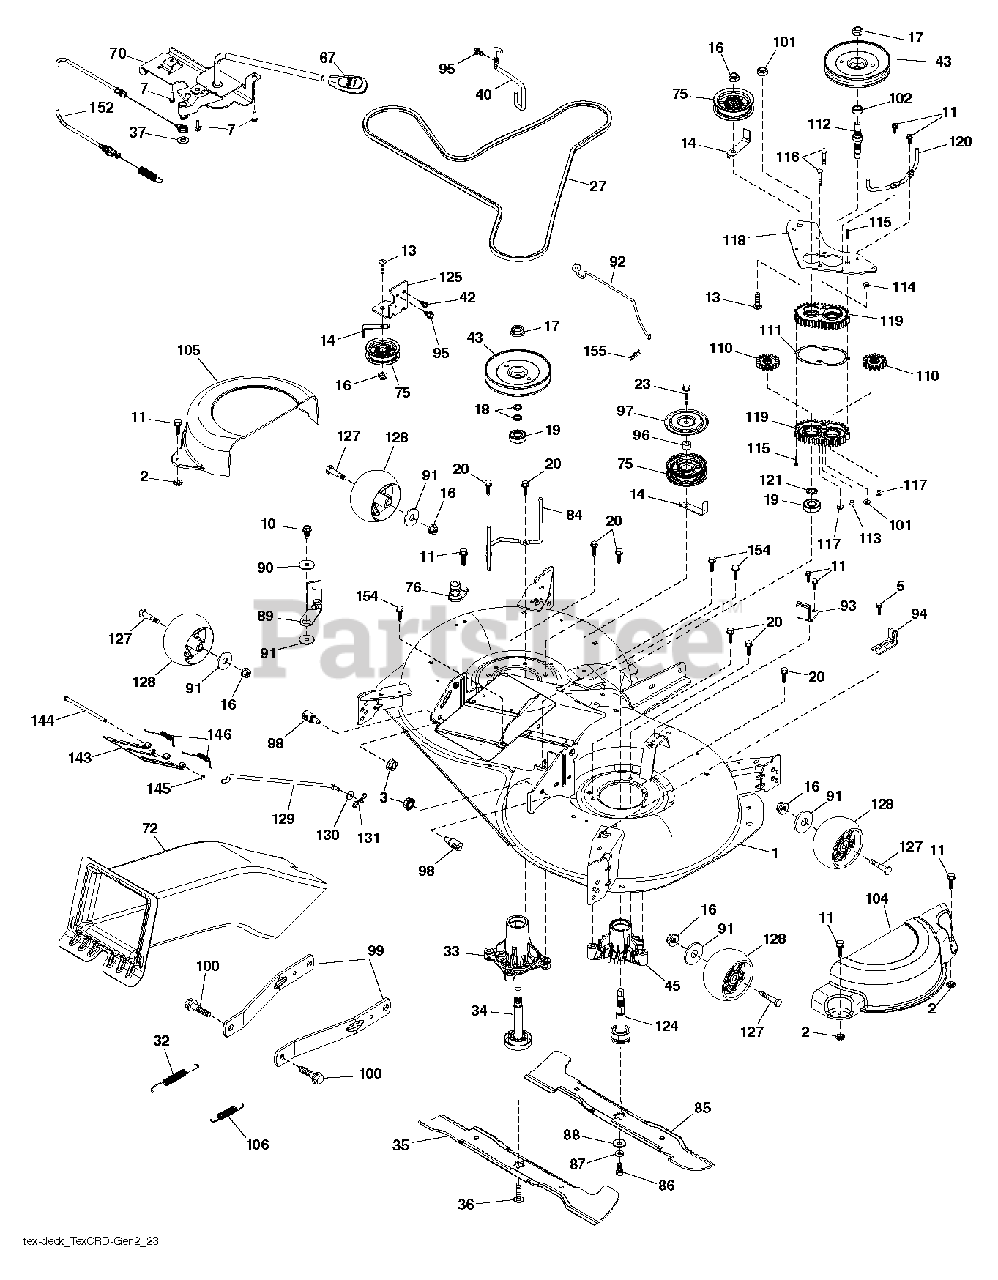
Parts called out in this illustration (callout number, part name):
2	PALNUT 1/4
3	NUT LOCK HEX FLANGE 5/16-18
5	BOLT.5/16HEX.WHS.HD
7	SCREW.#10 X 0.750.BOS THREAD
10	SCREW 3/8-16X1
11	SCREW.1/4-20X5/8
13	BOLT.3/8-16X1.50
14	KEEPER, BELT IDLER
16	NUT LOCK FLG 3/8-16 UNC
17	NUT.FLANGE.LOCK.TOP
18	WASHER.SPACER.MANDREL
20	SCREW, WASHER HEAD
23	SCREW LT
32	SPRING RETURN
36	BOLT.WASHER.ASM.7/16-2
40	KEEPER BELT ENGINE LH
42	SCREW
67	HANDLE.CLUTCH.CABLE.LT
70	CLUTCH.ASM.MANUAL.YT.PREDATORQ
75	FLAT IDLER PULLEY
76	PORT.WASHOUT
87	LOCKWASHER
88	WASHER.BLADE
89	ARM BRAKE MOWER
90	SPACER.RETAINER
94	BRKT.CLUTCH.CABLE
95	SCREW, 3/8-16X3/4
98	STUD.FASTNER.W/ANTI-ROTATE
99	ARM.SUSPENSION.MOWER.R
100	BOLT.SHOULDER
102	SPACER BEARING
106	SPRING.BRAKE.RETURN.38"
117	NUT T
127	BOLT.SHOULDER.3/8-16X3-5/8
128	WHEEL. GUAGE RALLY
130	WASHER
131	PIN.COTTER.5/16.BOW TI
145	E-RING.5/16"
155	RETAINER M
